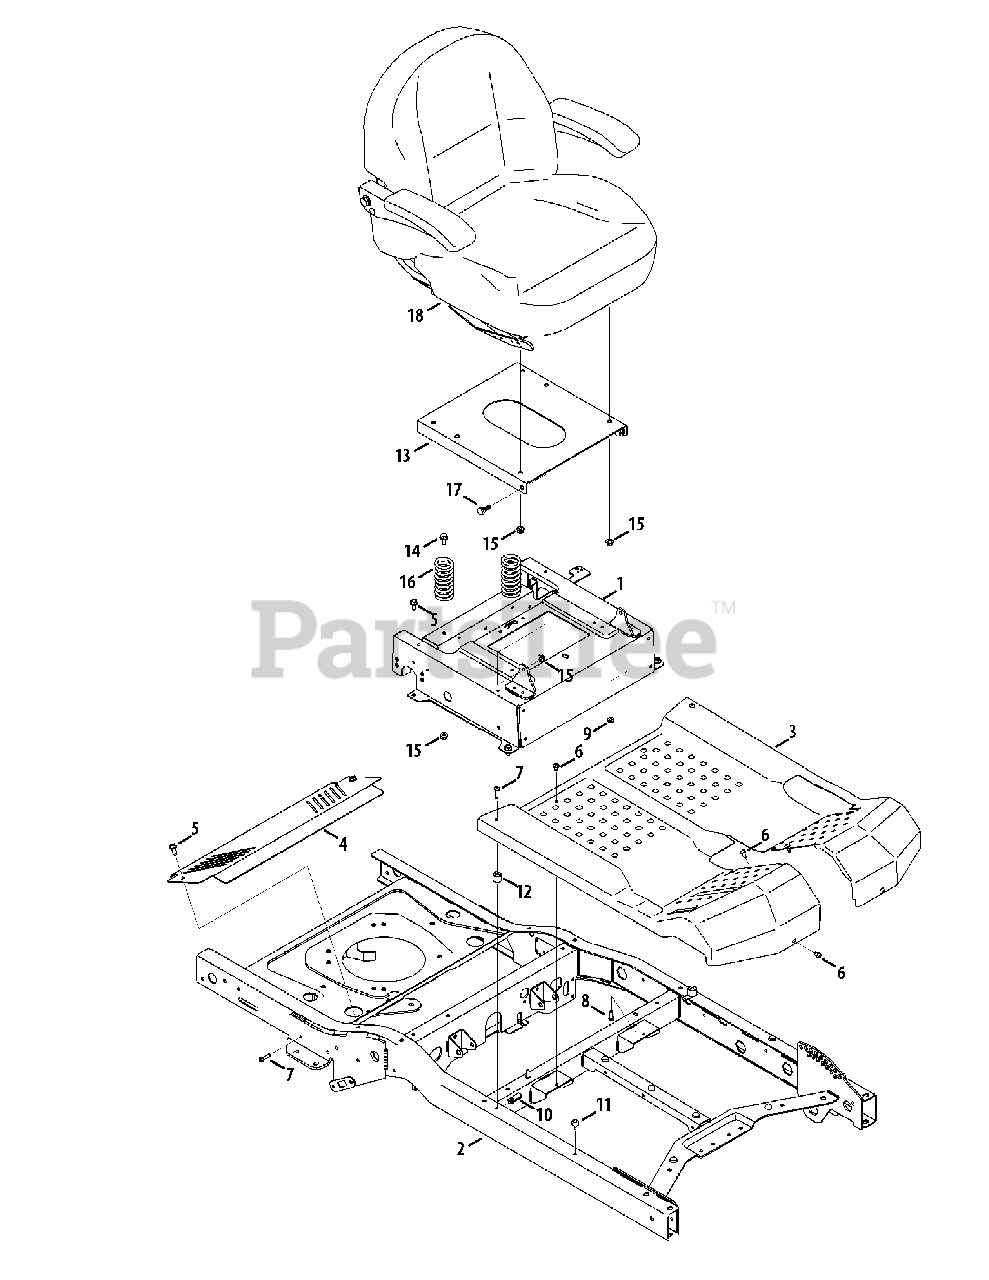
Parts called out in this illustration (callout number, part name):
5	Hex Washer Screw, 5/16-18 x .750
6	Screw, 1/4-20 x .5
7	Screw, 1/4-20 x 1.0
8	Hex Screw, 1/4-20 x .75
9	Flange Lock Nut, 1/4-20
10	Speed Nut, 1/4-20, U-Type
11	Bumper, .62 x .22
12	Spacer, .281 x .750 x .680
13	Seat Base
14	Hex Washer Screw, 5/16-18
15	Flange Lock Nut, 5/16-18
16	Comp. Spring, 1.71 x 3.735 x .238
17	Shoulder Screw, 5/16-18 x .437 x .268
18	Seat w/ Arms
